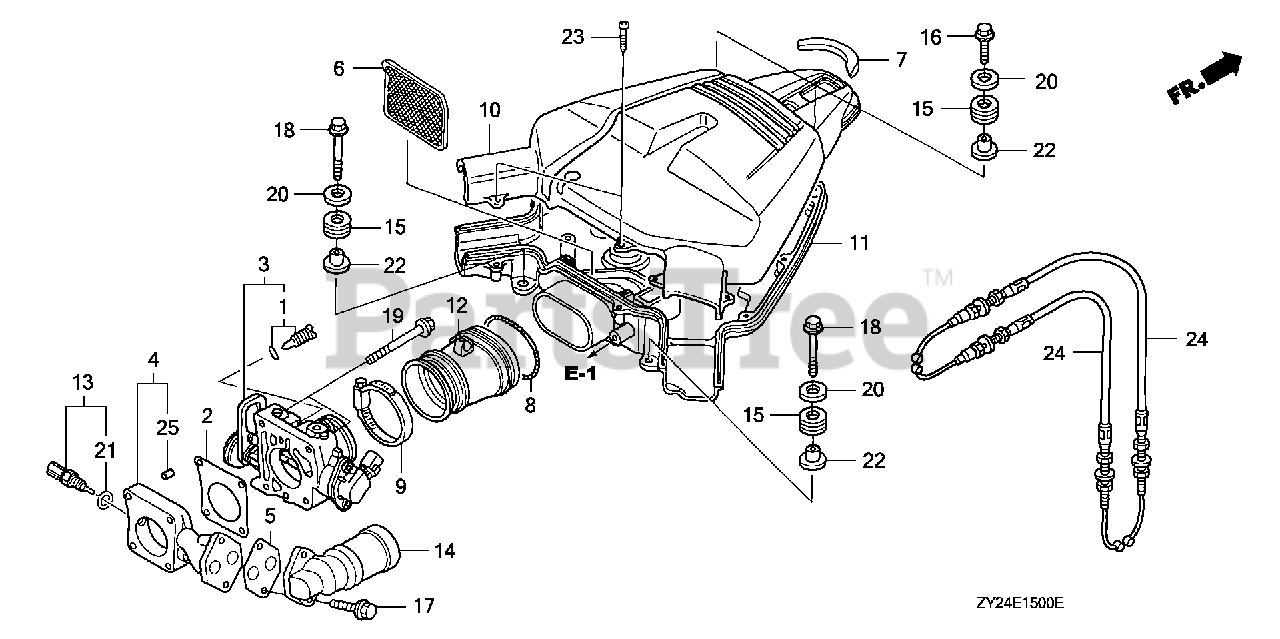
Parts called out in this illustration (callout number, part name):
2	GASKET, THROTTLE BODY
3	BODY ASSY., THROTTLE
4	SPACER, THROTTLE BODY
5	GASKET, EAC VALVE
6	TRAP, FLAME
7	RUBBER, SEAL MUFFLER
8	SPRING, AIR FLOW TUBE
9	CLAMP, AIR FLOW TUBE
9	BAND, AIR FLOW
10	CASE A, MUFFLER
11	CASE B, MUFFLER
12	GROMMET, MUFFLER
13	SENSOR ASSY., AIR TEMPERATURE
14	VALVE ASSY., EAC
15	GROMMET, CASE (LOWER)
16	BOLT, FLANGE (6X25)
17	BOLT, FLANGE (6X22)
18	BOLT, FLANGE (6X60)
19	BOLT, FLANGE (8X65)
20	WASHER, PLAIN (6MM)
22	COLLAR, MODULE IGNITION CONTROL CASE (CDI)
23	SCREW, TAPPING (5X20)
24	CABLE, THROTTLE
25	PIN, DOWEL (6X10)
